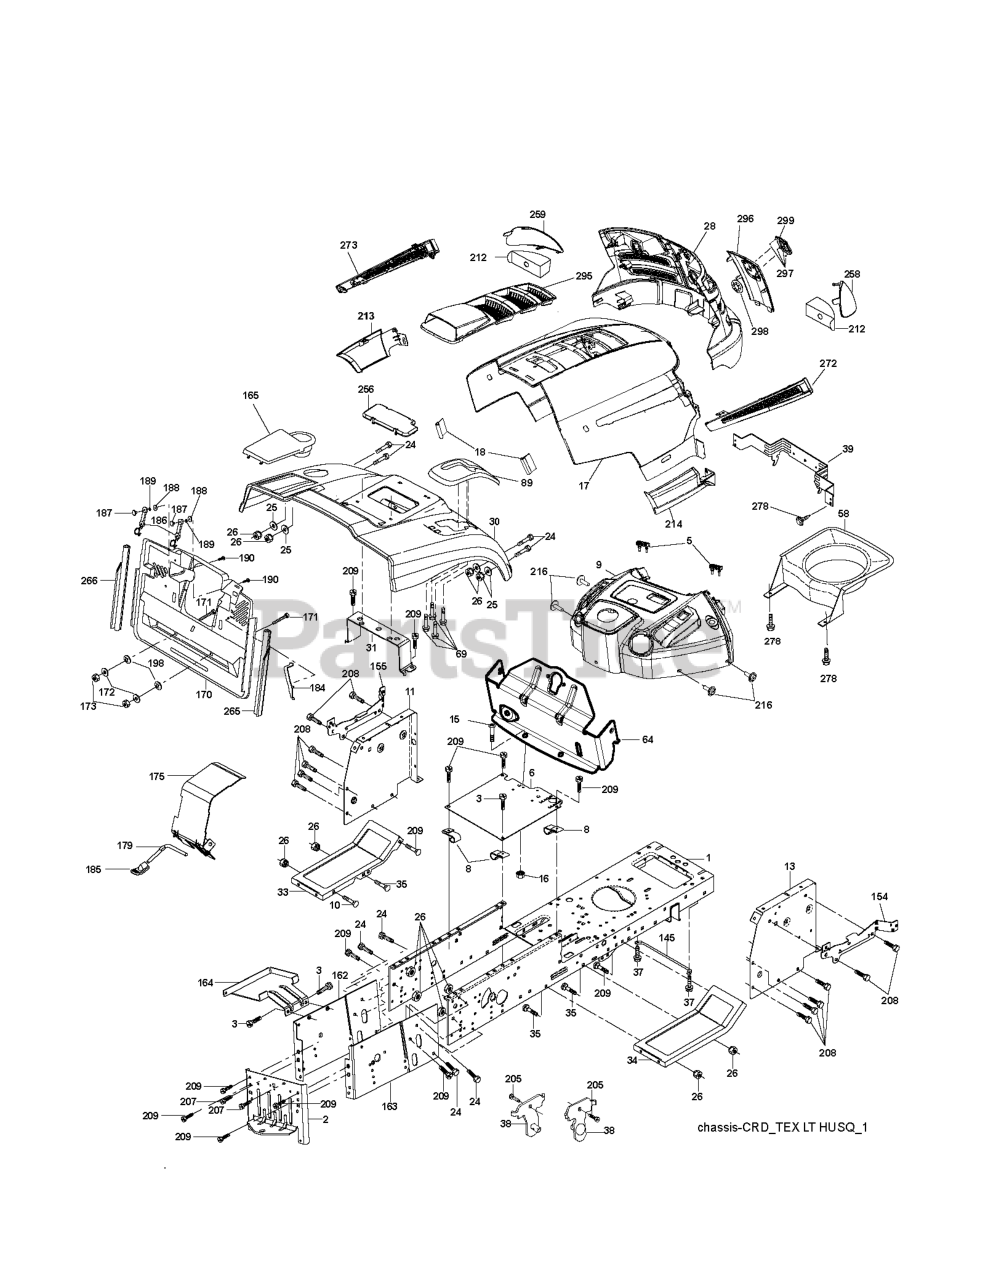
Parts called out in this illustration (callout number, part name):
2	DRAWBAR
3	SCREW 3/8-16X3/4
5	BUMPER DASH
6	PLATE
8	CLIP,INSULATOR
10	BOLT D
11	PANEL.DASH.LH.LTX
13	PANEL ASM, DASH RH
15	Screw, Machine, Truss Head 5/16-18 UNC x 3/4
16	NUT
17	HOOD
18	BUMPER.HOOD.TEX.HUSQVARNA
24	BOLT
25	WASHER
26	NUT
28	RP GRILLE/LENS ASM.
30	CONSOLE.CRD.AUTO.GRY
31	BRACKET SUPPORT FENDER
33	FOOTREST PNT LH
34	FOOTREST PNT RH
35	BOLT
37	Screw 5/16-18 x 1/2 Hex, Self Tapping 5/16-18 x 1/2
38	BRACKET ASM PIVOT MOWER REAR
39	BRACKET PIVOT
69	SCREW.HI-LO.CONSOLE
145	ROD.PIVOT.HOOD
162	BRACKET
163	BRACKET EXTEN CHASSIS RH CRD
165	RP.COVER.BATTERY.CRD.GREY
171	BOLT
172	WASHER
175	DOOR TRAP
179	ROD PIVOT FBI
184	BRACKET.ACTUATOR.BAGGER.SRD
186	LATCH ASSY
187	WELDNUT
189	LOCKWASHER #10
190	SCREW
205	SCREW LT
207	SCREW, 5/16-18 X 1/2
208	SCREW 3/8-16X1/2
209	SCREW, 3/8-16X3/4
212	INSERT REFLECTIVE
213	SKIRT SIDE LH
214	SKIRT SIDE RH
216	SCREW HEXWSHR 1/4-20X3/4
256	COVER FENDER CRD
258	LENS.HUSQVARNA LT.RH
259	LENS.HUSQVARNA LT.LH
265	SEALING
266	SEALING
272	VENT SIDE HOOD RH
273	VENT SIDE HOOD LH
278	SCREW.#10 X 0.750.BOS
295	VENT TOP HOOD
296	TRIM
297	CLIP.RETAINER.TINNER.
298	NUT PUSH M
299	RP LOGO
